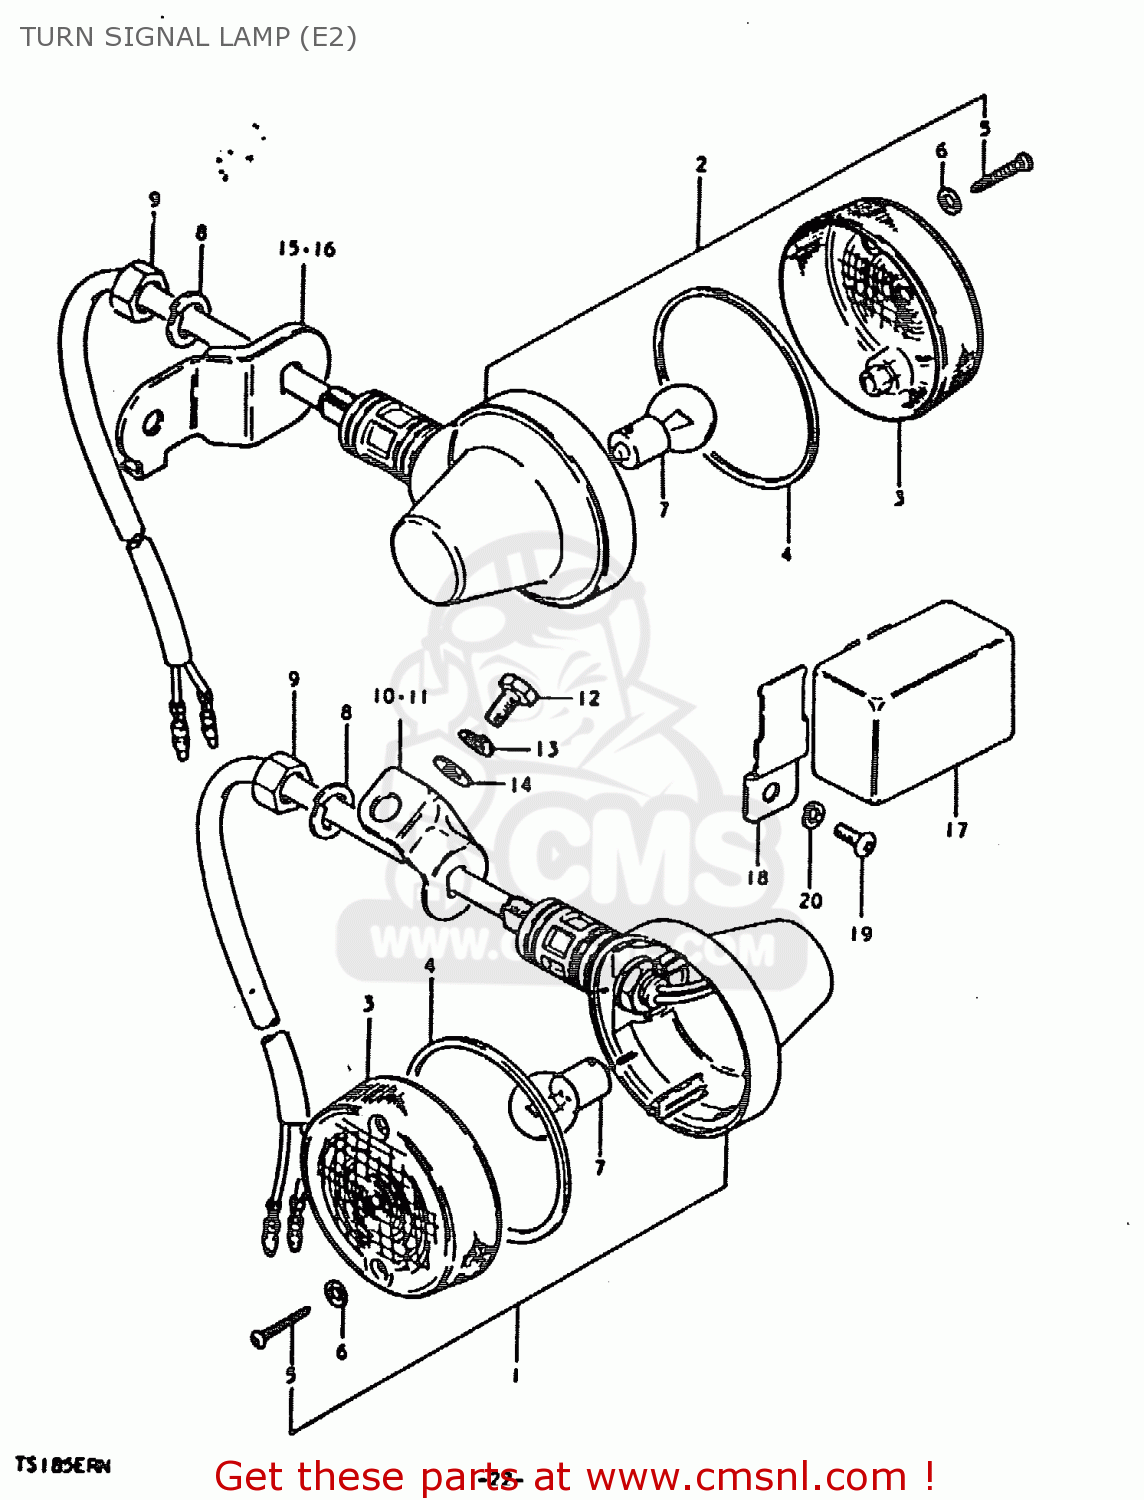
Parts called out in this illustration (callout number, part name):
1	LAMP ASSY,RR TURNSIGNAL
2	LAMP ASSY,RR TURNSIGNAL
3	LENS
4	GASKET (NAS)
5	SCREW TAPP.
6	GASKET (NAS)
7	BULB (6V,18W)
8	WASHER,LOCK 12
9	NUT
10	BRACKET,TURN SIGNAL LAMP
11	BRACKET,TURN SIGNAL LAMP
12	BOLT
13	LOCK WASHER
14	WASHER
15	BRACKET,REAR TURN SIGNAL
16	BRACKET,REAR TURN SIGNAL
17	RELAY,TURN SIGNAL
18	BRACKET,TURN SIGNAL RELAY
19	SCREW 6X12
20	LOCK WASHER
